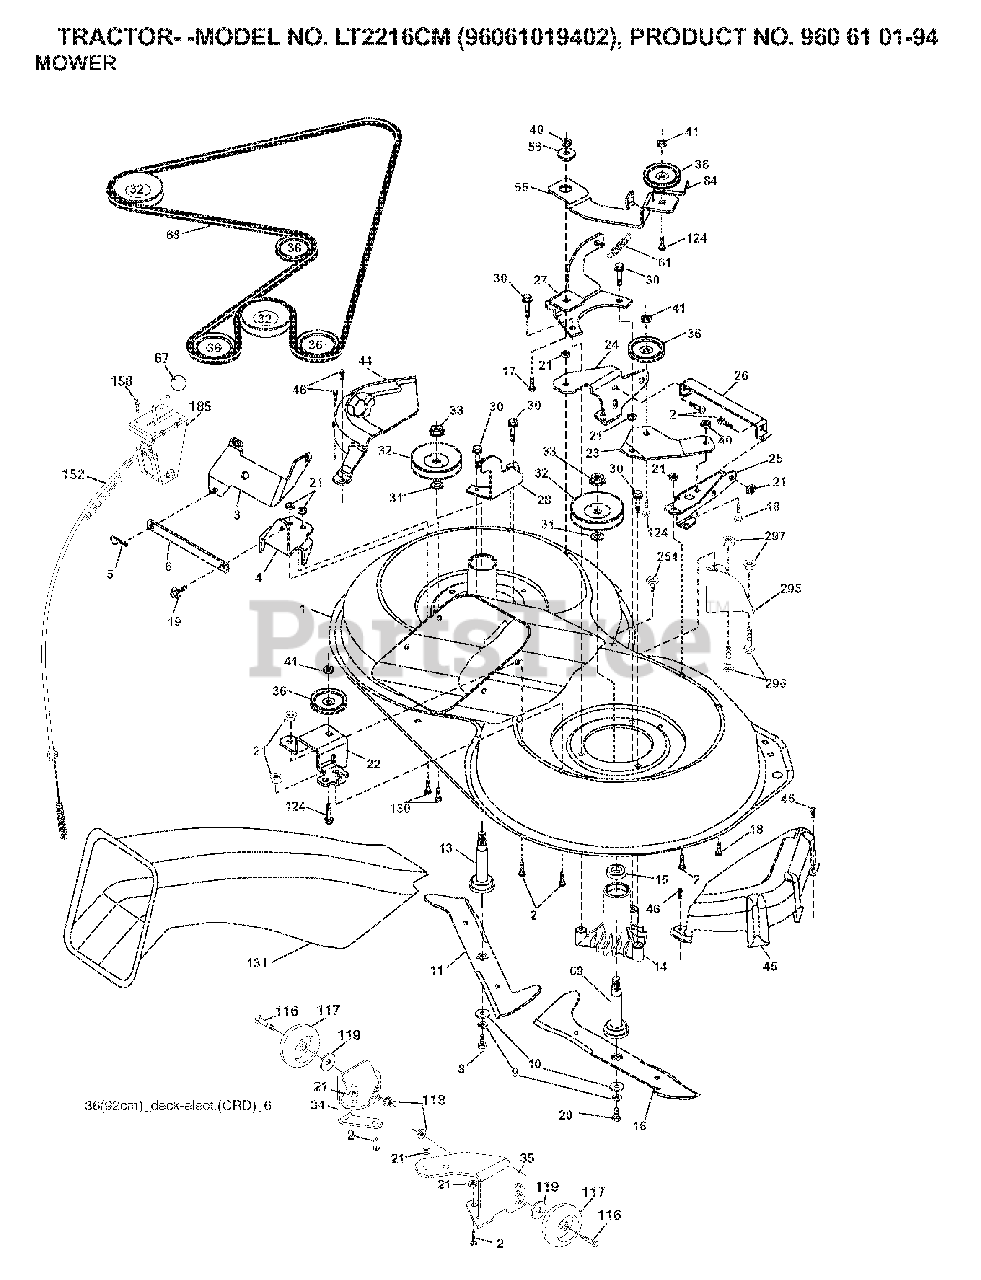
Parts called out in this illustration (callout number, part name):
2	BOLT
3	BRACKET
5	RETAINER-SPRNG RB
6	BAR SWAY
9	LOCKWASHER
10	WASHER.BLADE
13	SHAFT ASM VENT
14	HSG MANDREL
17	BOLT.3/8-14X1.25
19	BOLT SHD 5/16-18
21	LOCKNUT
24	BRACKET
25	BRACKET
28	BRACKET
30	SCREW, WASHER HEAD
31	WASHER.SPACER.MANDREL
32	PULLEY MANDREL
33	NUT.FLANGE.LOCK.TOP
36	PULLEY.IDLER.4.25
40	LOCKNUT
41	NUT LOCK FLG 3/8-16 UNC
45	MANDREL COVER
46	SCREW.1/4-20X5/8
56	SPACER.RETAINER.MOWER
67	KNOB T (3/8 HOLE)
69	SHAFT.ASM.W/LWR.BRG.RH.THREAD
84	KEEPER, BELT IDLER
116	BOLT.SHOULDER.3/8-16X3-5/8
117	WHEEL. GUAGE RALLY
118	NUT LOCK FLG 3/8-16 UNC
124	BOLT.3/8-16X1.50
131	CHUTE BAGGER
158	SCREW
185	HEAD ASM. CABLE CLUTCH
254	SCREW 3/8-16X1
296	BOLT
297	NUT CENTERLOCK
